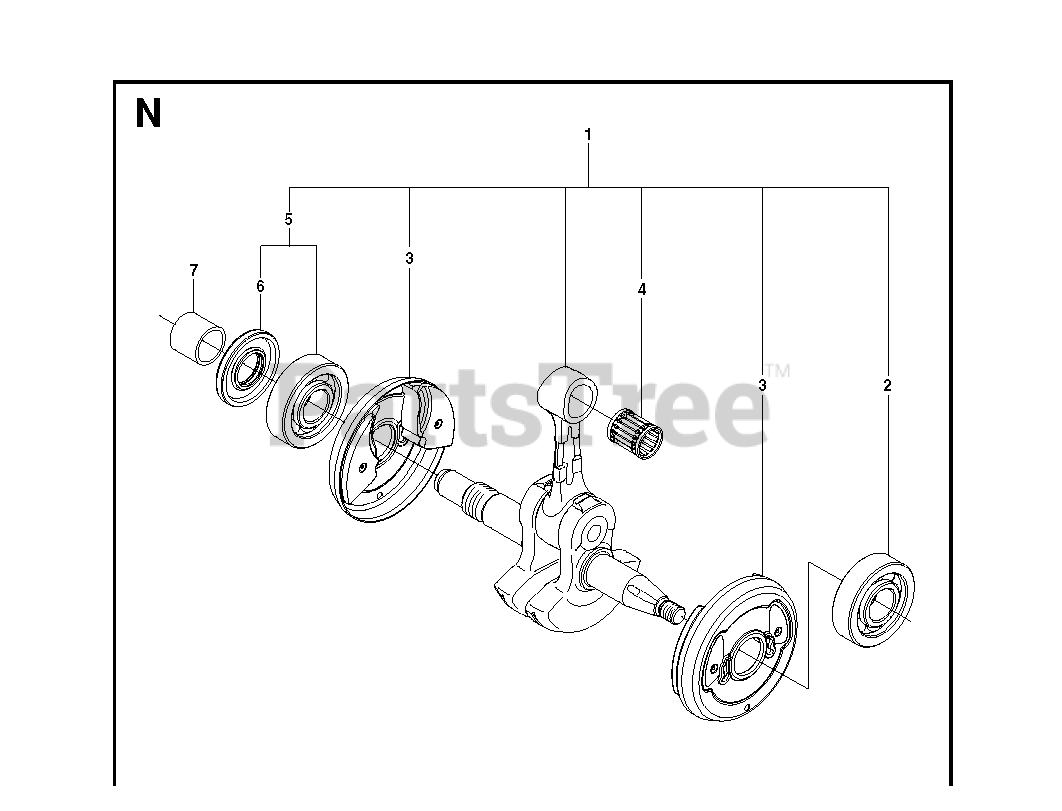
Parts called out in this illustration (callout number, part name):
1	CRANKSHAFT
2	BALL BEARING-6202-C3 SKF
4	SUPPORT BUSHING
5	%BALL BEARING
6	RADIAL SEAL
